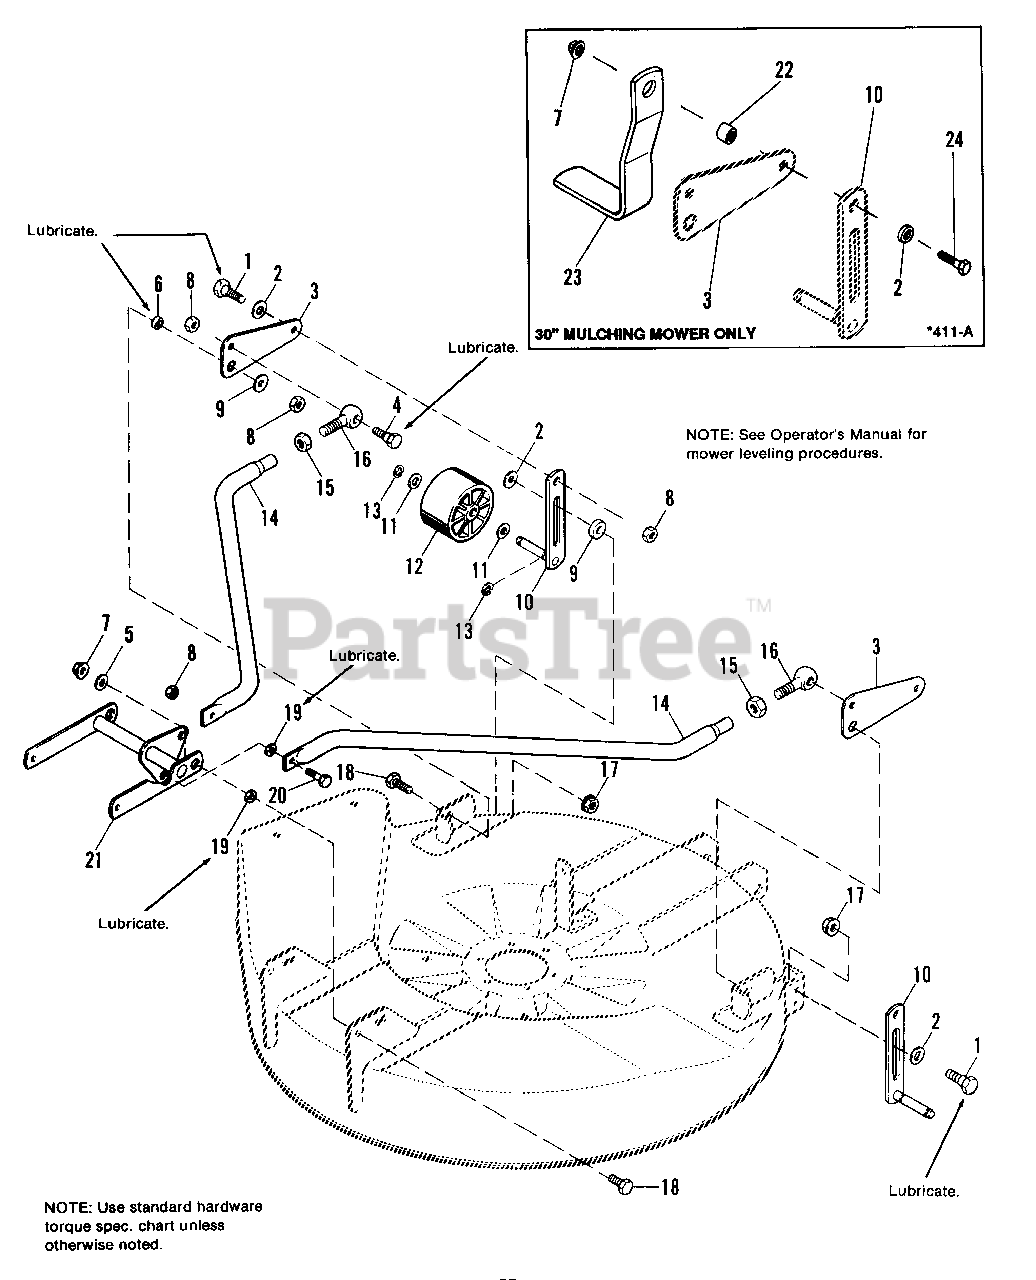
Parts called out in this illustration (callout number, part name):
1	BOLT, Shoulder, 3/8-16 X 1.34
2	WASHER, Plain, 7/16
4	BOLT, Shoulder
5	WASHER
7	LOCKNUT, Flange, Centerlock 3/8-16 (Qty. 2 on 1691437)
8	NUT, Full, Whizlock 3/8-16
10	ROLLER SUPPORT ASSY.
11	WASHER, Plain, 5/8
13	RING, Retaining
14	ARM, Adjusting
15	NUT, Jam, 1/2-20
17	LOCKNUT, Flange, Whiz, 3/8-16
18	CAPSCREW, Hex, 3/8-16 x 1
20	CAPSCREW, Hex, 3/8-16 x 1-1/4
21	SUPPORT ARM ASSY.
22	SPACER
23	BRACKET, Roller
24	BOLT, Shoulder, 3/8-16 X 1.34
